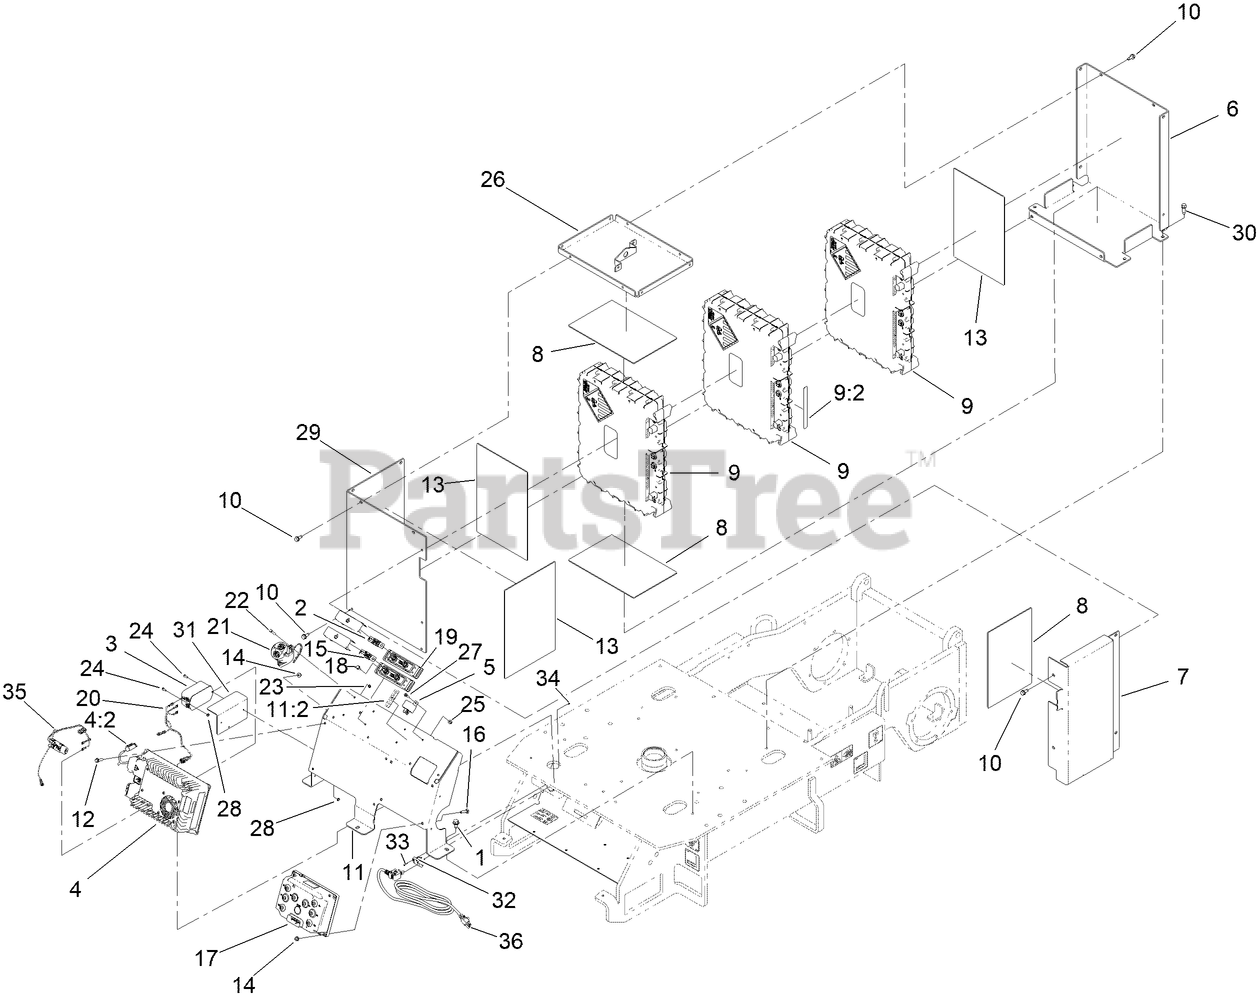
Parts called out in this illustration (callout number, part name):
1	SCREW-HWH
2	FUSE-200A
3	FILTER
4	CHARGER-ONBOARD
4:2	KIT-SERVICE, DC HARNESS
5	RELAY, 48V COIL, 50A AT 48V
6	MOUNT-BATTERY, BASE
7	COVER-BATTERY, SIDE
8	PAD-FOAM
9	BATTERY ASM
9:2	DECAL-WARNING, BATTERY
10	SCREW-THD ROLL, HWH
11	BRACKET-ELECTRICAL
11:2	DECAL-FUSE
12	SCREW-HFH
13	PAD-FOAM
14	NUT-FLANGE, NI
15	FUSE-70A
16	SCREW-CARR
17	INV/CTRLR-48V,DUAL 94Arms
18	SCREW-HWH
19	HOLDER-FUSE
20	HARNESS-WIRE, AC CHARGER
21	CONTACTOR-48V
23	NUT-LOCK
24	SCREW-PPH
25	NUT-HF
26	COVER-BATTERY [PRIMED]
27	SCREW-HWH
28	NUT-LOCK
29	COVER-BATTERY, SIDE
30	SCREW-THD FORM, HWH
31	BRACKET-FILTER
32	CONNECTOR-IEC
33	Ball, Governor
34	NUT-LOCK, NI
35	HARNESS-WIRE, AC CHARGER
36	CORD-AC, 120V
